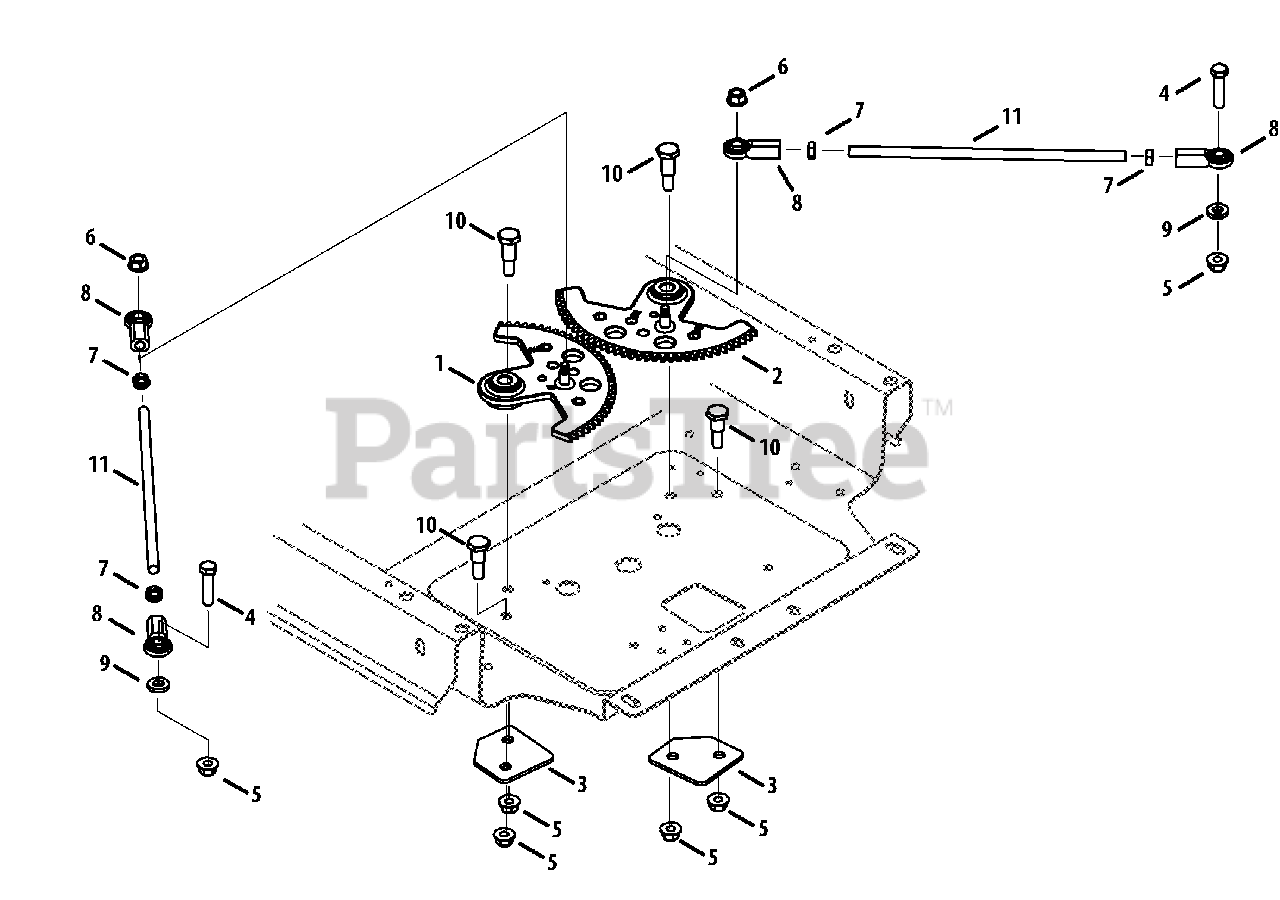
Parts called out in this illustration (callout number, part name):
1	Steering Gear Assembly, RH
2	Steering Gear Assembly, LH
3	Steering Support Plate
4	Hex Screw, 3/8-16 x 1.50
5	Flange Lock Nut, 3/8-16
6	Nut, 5/16-18, Centerlock
7	Jam Nut, 3/8-24
8	Female Ball-Joint
9	Flat Washer, .407 x .812 x .135
10	Shoulder Screw, 3/8-16 x .500 x .875
11	Drag Link, .375 Dia.
